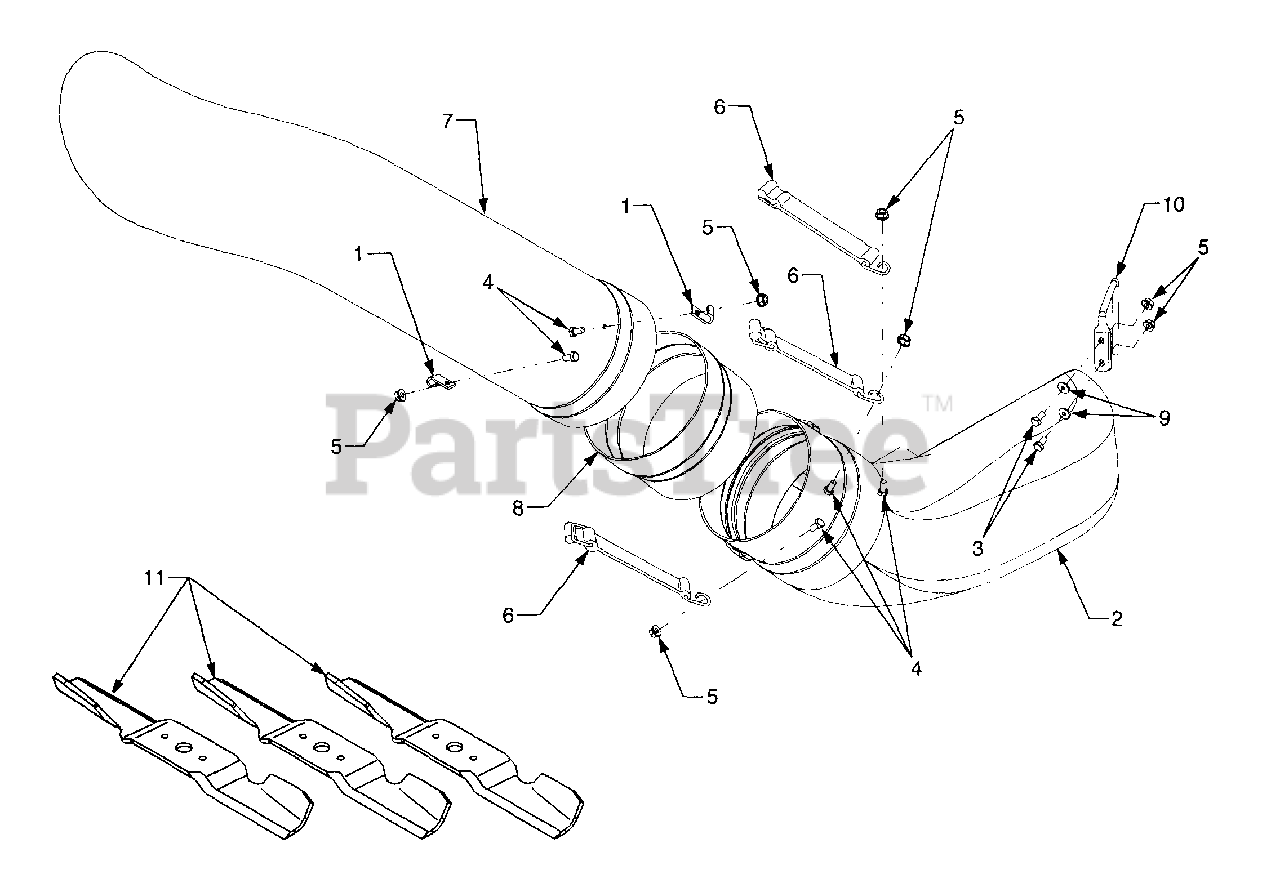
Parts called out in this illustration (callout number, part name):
1	Bracket, Retainer Hook
2	Chute Assembly, Elbow
3	Screw, Hex Wash. Hd. Tapp 1/4-20 x 75
4	Screw, Hex Cap, 1/4-20 x .62 GR5
5	Nut, Hex Flange Lock, 1/4-20 7
6	Strap Assembly, Retainer
7	Tube, Chute
8	Extension, Chute Tube 1
9	Washer, Flat, .28 x .74 x .063 2
10	Rod, Chute Mounting 1
11	Blade, High Lift 3
